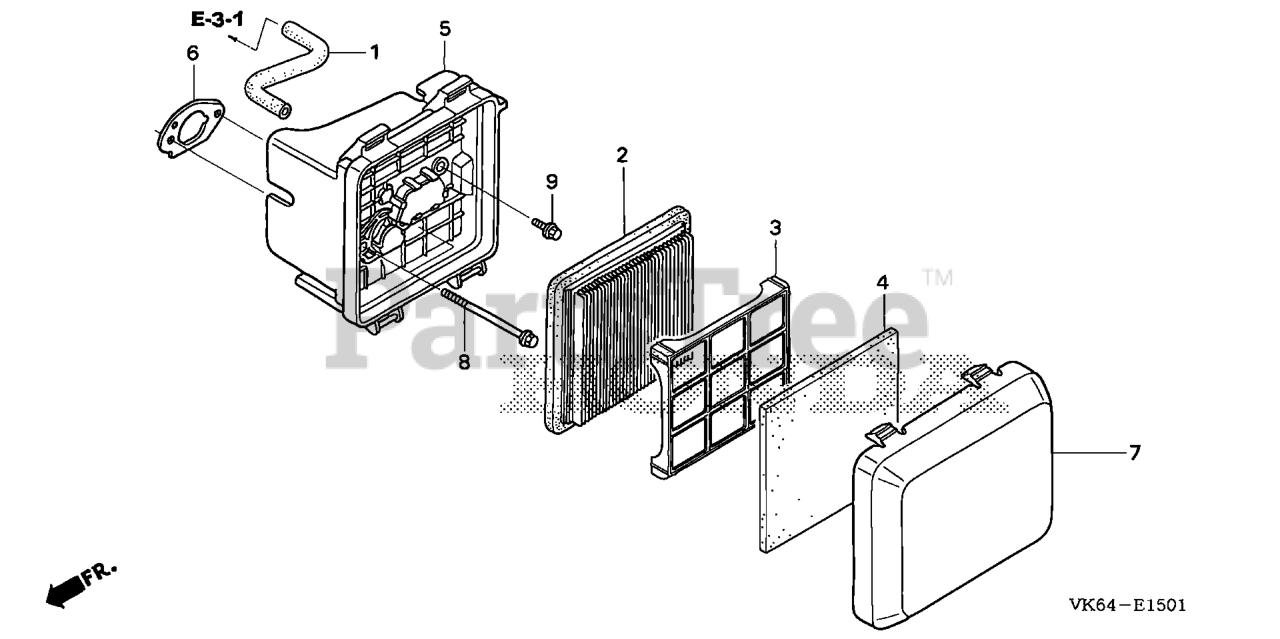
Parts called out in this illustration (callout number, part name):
1	TUBE, BREATHER
2	ELEMENT, AIR CLEANER (TOYO ROKI) (ENGINE NO.)
3	GRID, AIR CLEANER
4	FILTER (OUTER) (WET)
5	CASE ASSY., AIR CLEANER
6	GASKET, AIR CLEANER
7	COVER, AIR CLEANER (DUAL)
8	BOLT, FLANGE (6X85) (CT200)
8	BOLT, SPECIAL (6MM)
9	BOLT, FLANGE (6X14)
